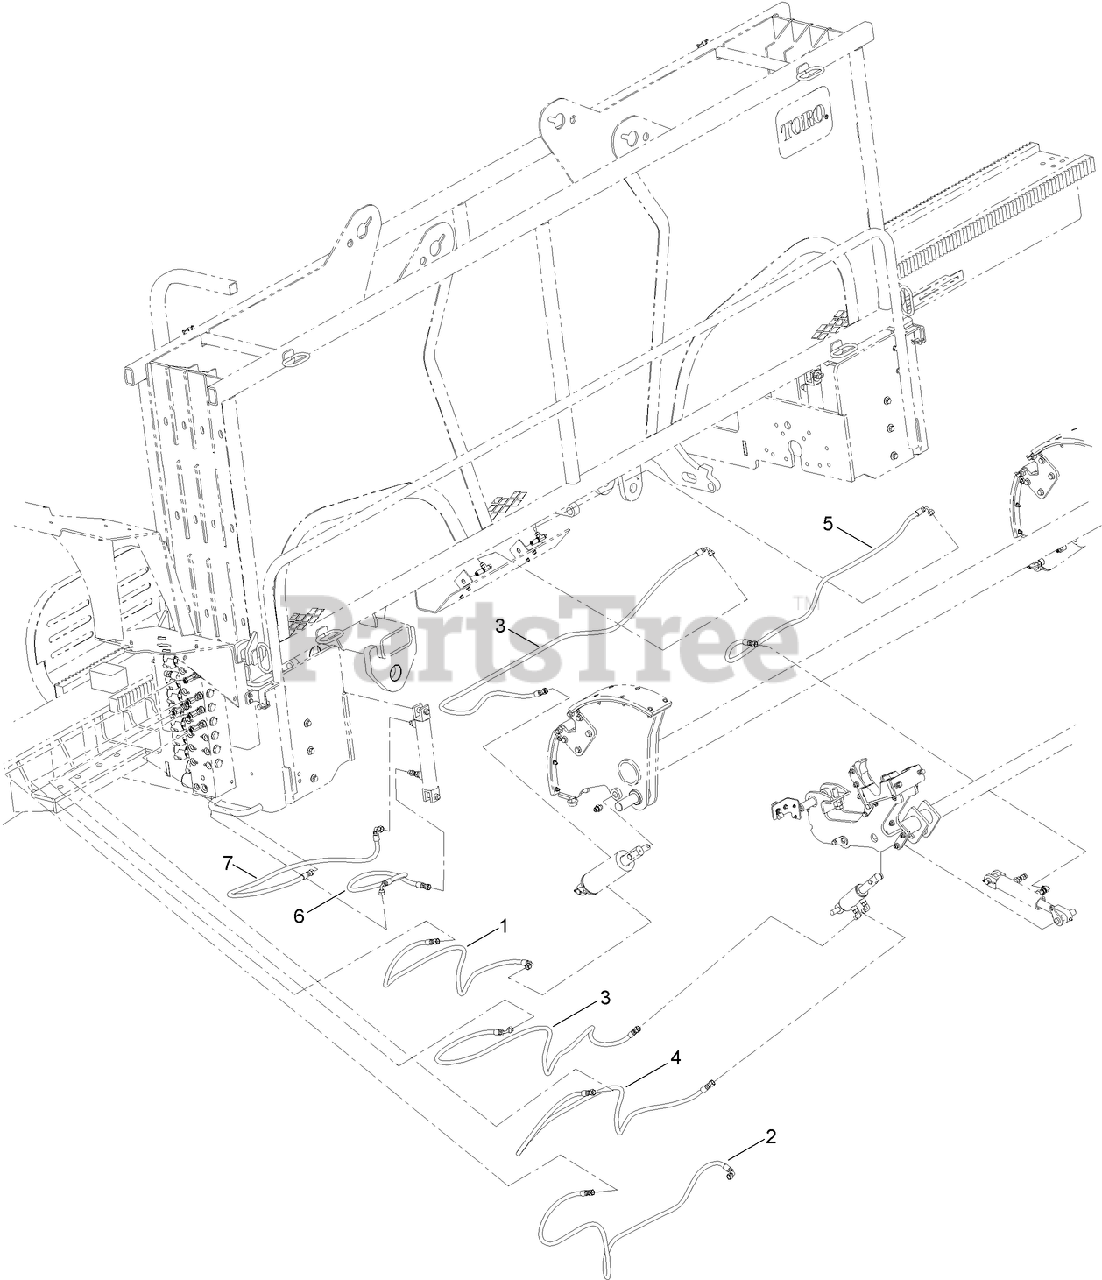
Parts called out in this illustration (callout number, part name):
1	HOSE ASM-HYD
2	HOSE ASM-HYD
3	HOSE ASM-HYD
4	HOSE ASM-HYD
5	HOSE ASM-HYD
6	HOSE ASM-HYD
7	HOSE ASM-HYD
